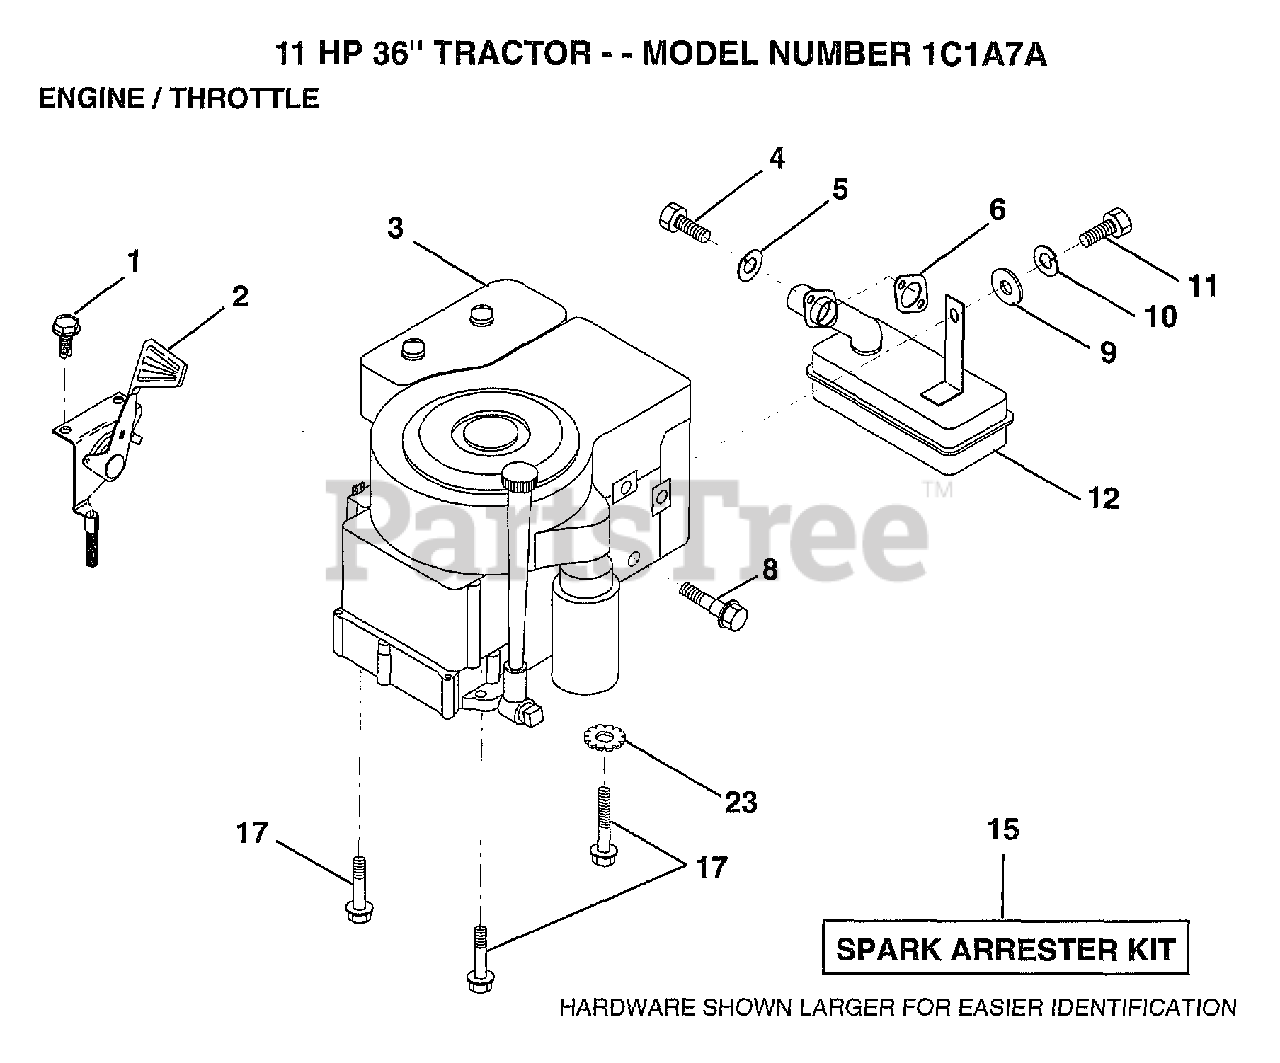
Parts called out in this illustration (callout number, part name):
1	SCREW.1/4-20X1/2
2	"CONTROL,THROTTLE"
4	SCREW
5	LOCKWASHER
8	BOLT T
10	LOCKWASHER
12	MUFFLER
17	SCREW LT
23	LOCKWASHER
